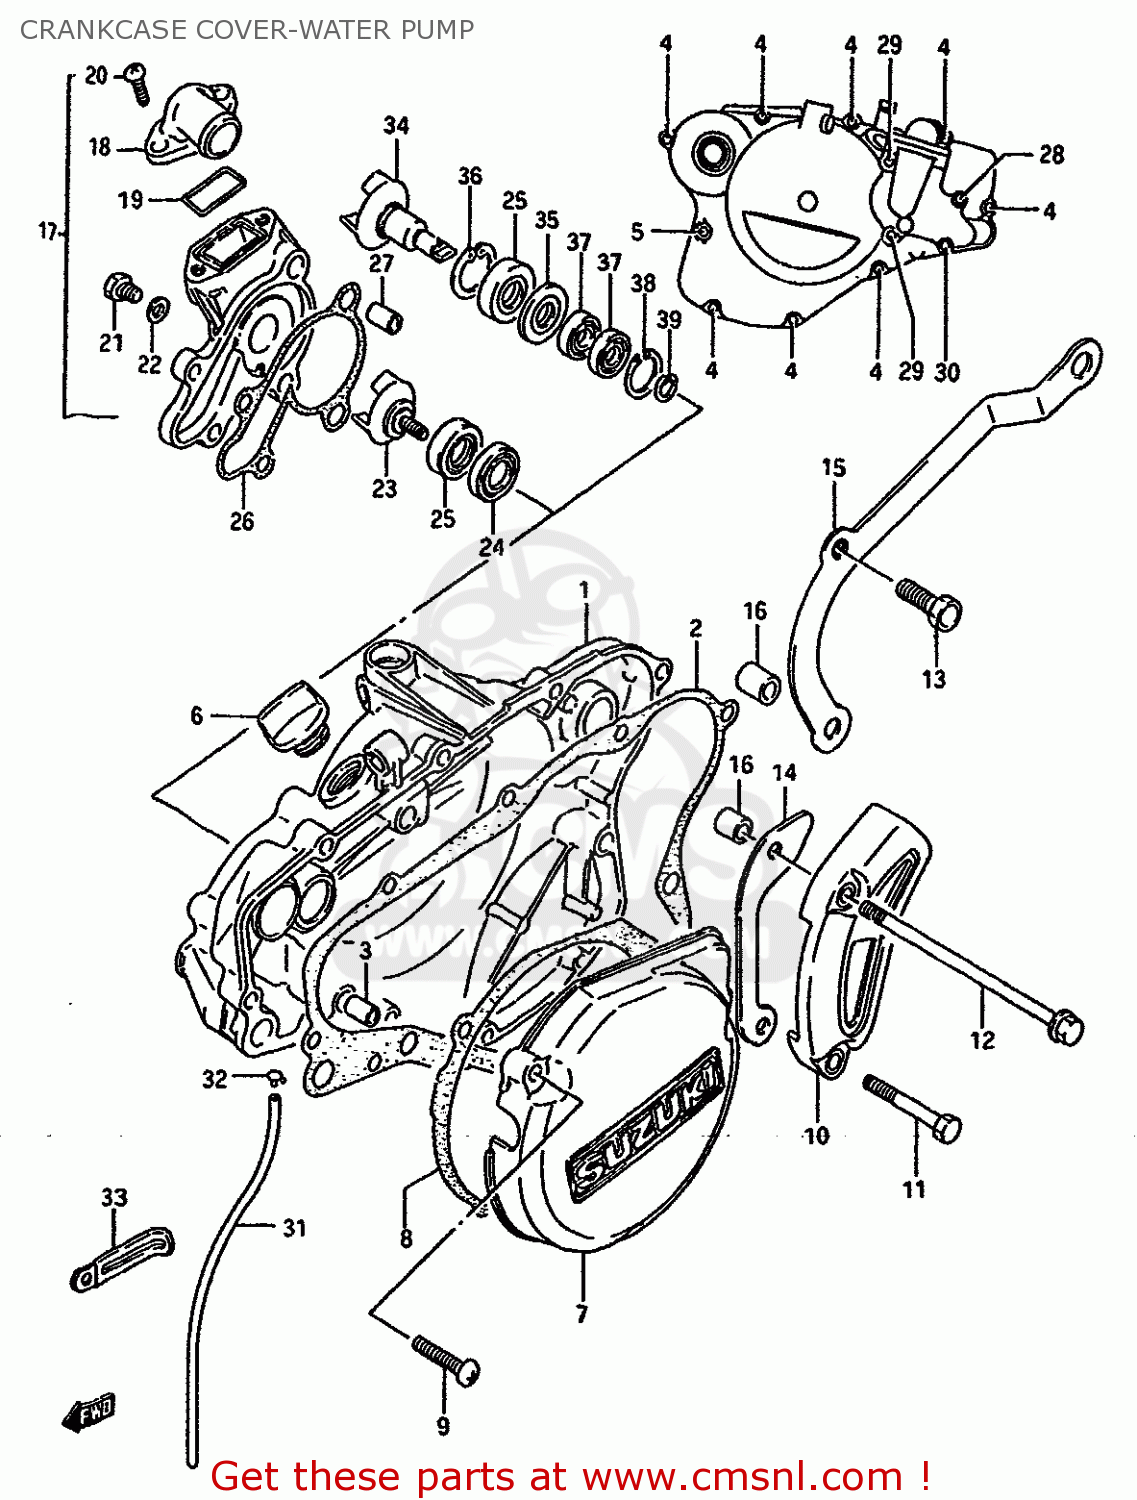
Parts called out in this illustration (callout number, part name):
1	COVER,CLUTCH
2	GASKET,CLUTCH COVER (MCA)
3	PIN
4	SCREW
5	SCREW
6	PLUG SET
7	COVER,MAGNETO
8	GASKET,MAGNETO COVER (MCA)
9	SCREW
10	COVER,SPROCKET
11	BOLT 6X40
12	BOLT(6X105)
13	BOLT
14	PLATE,CHAIN GUIDE
15	PLATE COMP,FRONT CHAIN
16	SPACER(6.5X10.5X12)
17	CASE,WATER PUMP
18	CONNECTOR
19	O RING,WATER PUMP CONNECTOR
20	SCREW
21	BOLT,BLEEDER
22	GASKET (NAS)
23	IMPELLER,WATER PUMP
24	SEAL,OIL(12X24X7)
25	SEAL,OIL(12X24X6.4)
26	GASKET,WATER PUMP CASE
27	PIN
28	SCREW
29	SCREW 6X30
30	SCREW 6X85
31	HOSE
32	CLIP
33	CLAMP
34	IMPELLER,WATER PUMP
35	SEAL,OIL(12X24X3.6)
36	CIRCLIP
37	BEARING
38	CIRCLIP
39	CIRCLIP
